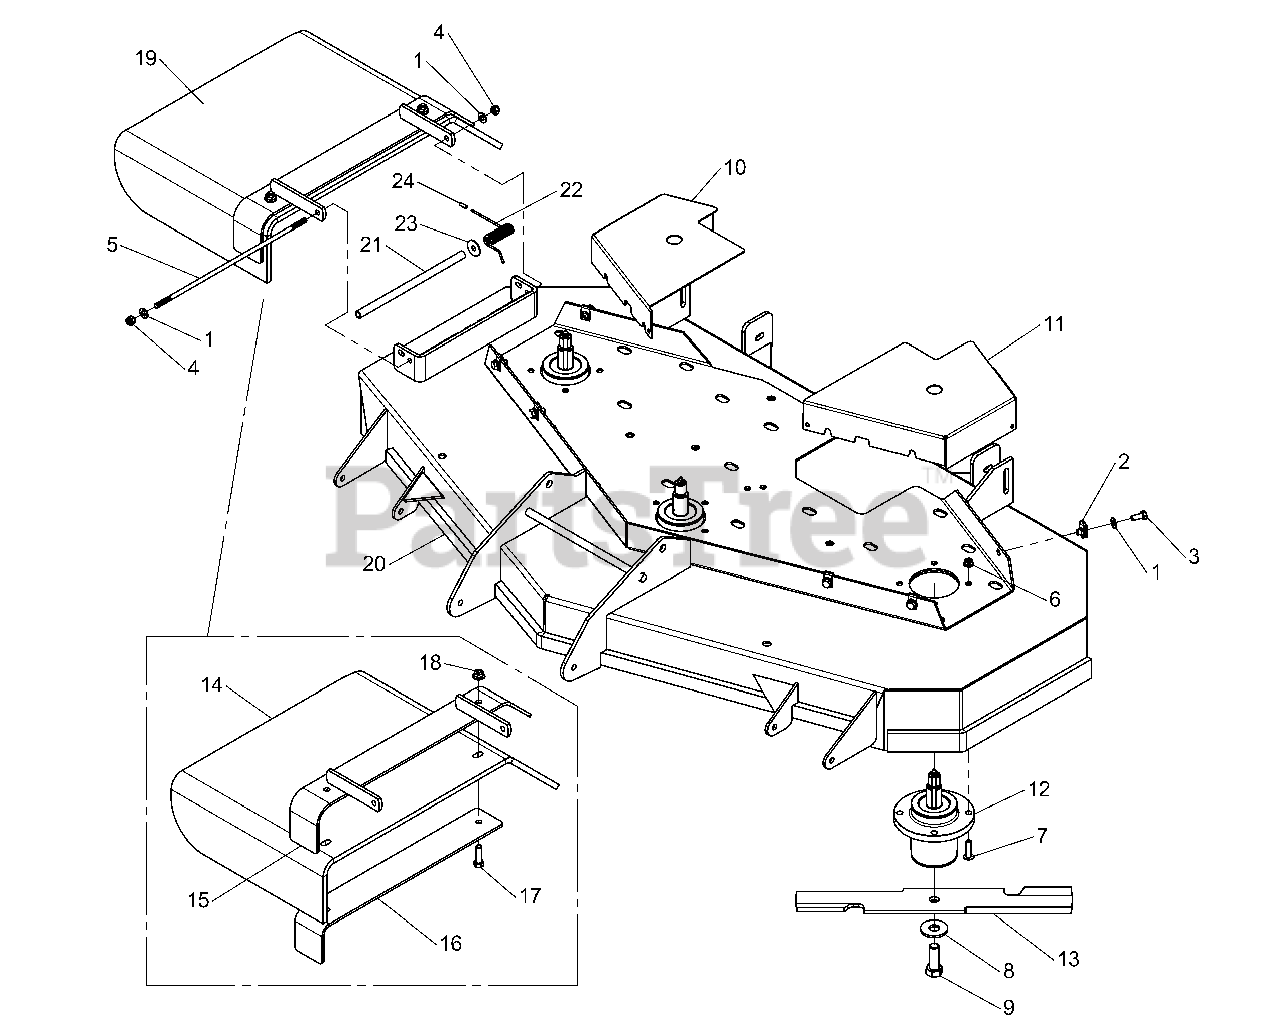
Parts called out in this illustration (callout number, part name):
1	WASHER, 5/16" SAE
2	BODY CLIP, 5/16-18
3	BOLT, 5/16-18 X 3/4"
4	NUT 5/16-24 Hex Nylon Lock
5	ROD, Linkage
6	NUT, 5/16-18 Hex Nylock Flange
7	BOLT, Flange Head, 5/16-18 x 1-1/4
8	WASHER, 5/8" USS
9	BOLT, 5/8-11 X 1-3/4"
10	GUARD, 48" DECK - RH
10	GUARD, 52" DECK - RH
11	GUARD, 48" DECK - LH
11	GUARD, 52" DECK - LH
12	SPINDLE ASSEMBLY, Complete (See Spindle Service Parts group)
13	MOWER BLADE, 16-1/4" (48" deck)
13	MOWER BLADE, 18" (52" Deck)
14	RUBBER CHUTE
15	WELD, FRAME CHUTE, 44/48/52 - BLK
16	SUPPORT, DISCHARGE CHUTE, 48/52 - BLK
17	BOLT, 3/8-16 X 1-1/4"
18	NUT, 3/8-16 Hex Nylock Flange
20	MOWER DECK ASSEMBLY, 48"
20	MOWER DECK ASSEMBLY, 52"
21	TORSION SPRING SPACER
22	TORSION SPRING
23	WASHER, 5/16" Fender
